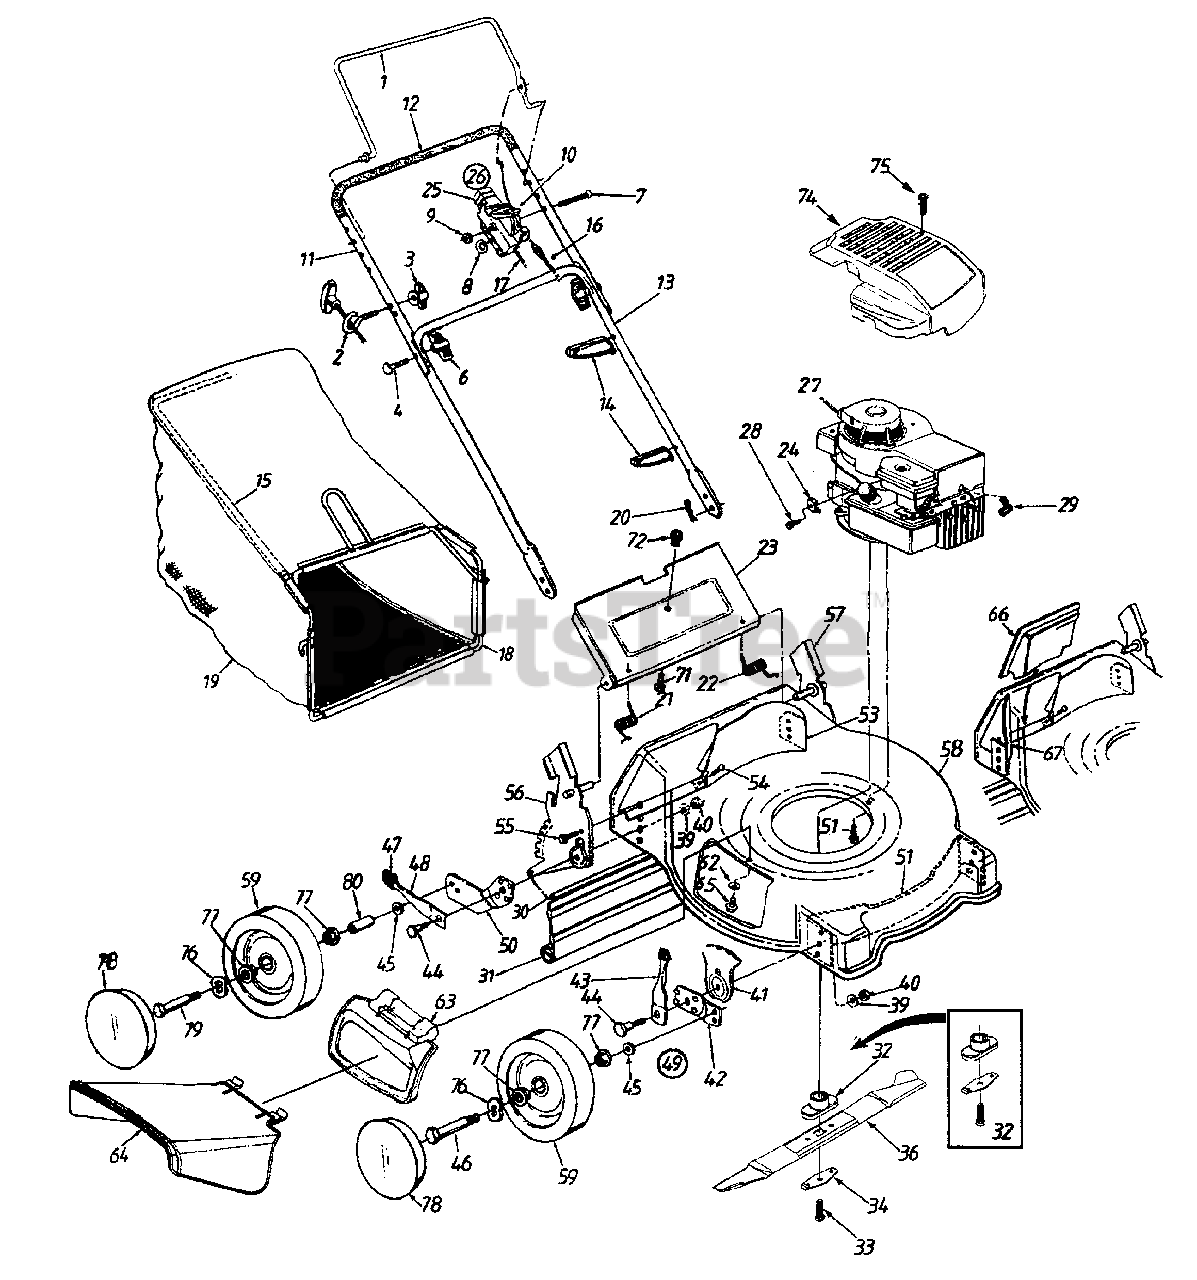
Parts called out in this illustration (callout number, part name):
1	Control Handle Ass'y.
2	Rope Guide
3	Handle Knob 1/4-20 Thd.
4	Curved Hd. Bolt 5/16-18 x 2" Lg.
6	Hand Knob
7	Oval C-Sunk Mach. Scr.
8	Spr. Wash. .66" I.D.
9	Hex L-Nut 1/4-20 Thd.
10	Throttle Lever
14	Cable Tie
16	Control Cable-36"
17	Throttle Control Wire-55"
20	Int. Cotter Pin 5/16" Dia.
21	Door Spring-R.H.
22	Door Spring-L.H.
25	Throttle Body
26	Throttle Box Comp.
27	Engine
28	Hex Wash. Hd. Scr. #10-32 x .62" Lg.
29	Spark Plug Boot
30	Wire Rod
31	Rear Flap
32	Blade Adapter Kit
33	Hex Bolt 3/8-24 x 1.5" Lg.
34	Blade Bell Support
36	21" Mulching Blade
39	Bell-Wash. .39" I.D. x 1.38"
40	Hex Nut 3/8-16 Thd.
41	Height Adj. Plate
43	Spring Lever Ass'y. w/Knob
44	Shld. Bolt .5" Dia. x .357"
45	Bell-Wash. .38" I.D. x .88" O.D.
46	Front Axle Bolt
47	Spring Lever Knob
48	Spring Lever
49	Height Adj. Ass'y. Comp.-R.H.
50	Pivot Bar R.H.
54	Torx Mach. AB-Tap Scr. 1/4 x .62" Lg.
55	Hex L-Wash. Hd. AB-Tap Scr. 1/4 x .62" Lg.
62	Bell-Washer 1/4" I.D.
63	Hinged Mulching Plug
64	Chute Deflector
65	Hex Head Self-Tap Scr. 1/4-20 x .5" Lg.
71	Truss Scr. #10-24 x .38" Lg.
74	Hi-Lo Scr. #10 x 1.25" Lg.
75	XTE Black Shroud
76	Wave Washer
77	Ball Bearings
78	Hub Cap
79	Rear Axle Bolt
80	Spacer
